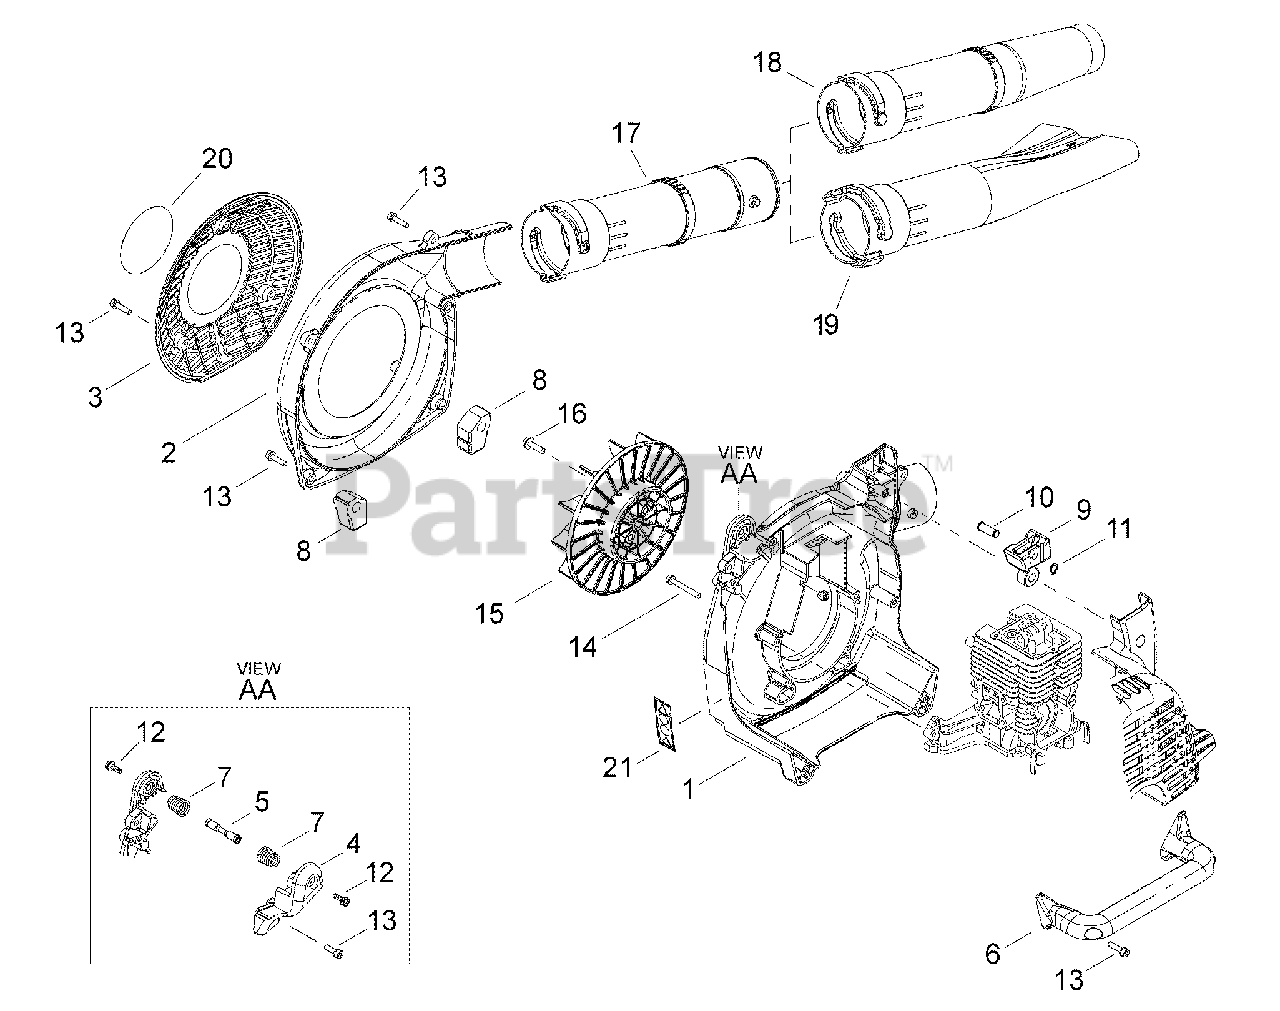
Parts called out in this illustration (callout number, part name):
1	CASE, FAN
2	COVER, FAN
3	COVER, INTAKE
4	MOUNT, HANDLE
5	NUT, HANDLE 5
6	HANDLE, SIDE
7	SPRING, COIL Ø18ר14
8	CUSHION
9	CUSHION, AV
10	PIN, LOCK
11	RING, SNAP 8 MM
12	SCREW, ADHESIVE M5×16
13	BOLT M5×20
14	BOLT M5×40
15	FAN
16	BOLT M6×20
17	TUBE, BLOWER
18	TUBE, BLOWER - ROUND NOZZLE
19	NOZZLE, FAN TIP
20	LABEL, E4 A4000
21	LABEL, CAUTION
